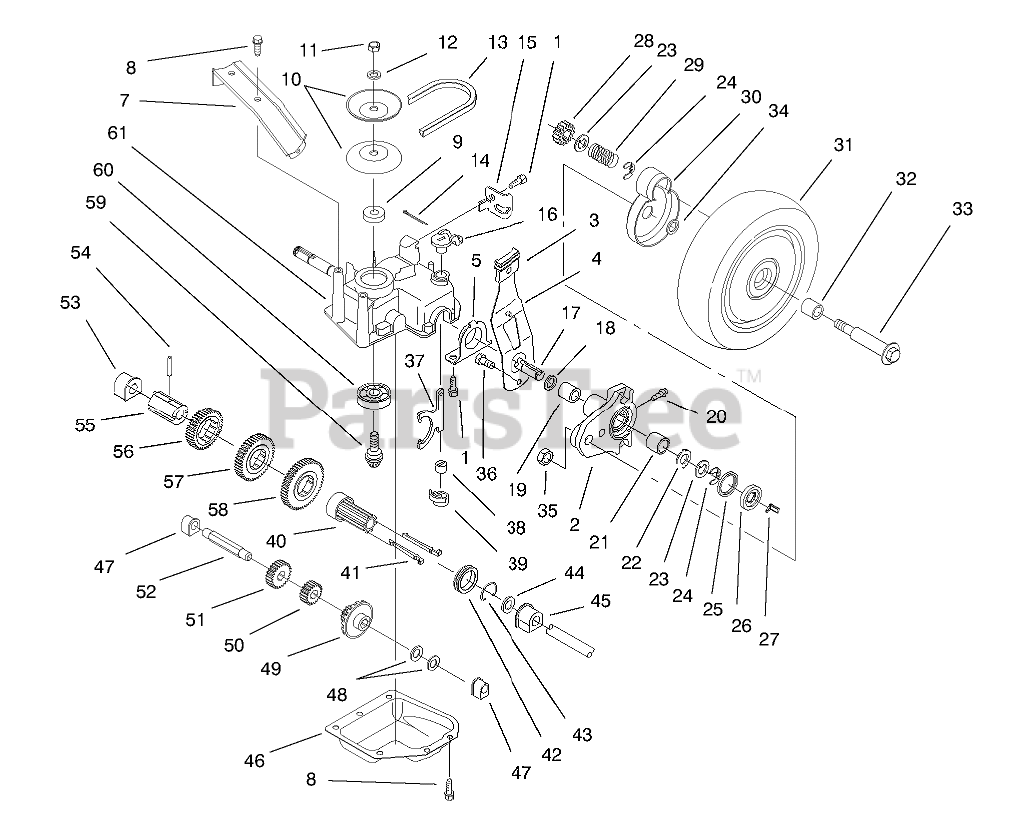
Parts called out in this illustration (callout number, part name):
1	SCREW-HWHTF
2	Pivot Arm Assembly (Incl. Ref. #19-21)
3	KNOB-ARM
4	SPRING ARM ASM
5	CAP-END
7	Bracket-BeltGuide
8	SCREW-HWHTF
9	SPACER
10	Pulley Half
11	NUT-HEX
12	WASHER-FLAT
13	V-BELT
14	PIN-COTTER
15	RETAINER-CABLE
16	LEVER-SHIFT
17	SHAFT-OUTPUT
18	O-RING
19	BUSHING
20	FITTING-GREASE
21	BEARING-ROLLER
22	WASHER-ARM, PIVOT
23	WASHER-THRUST, KEYED
24	RING-CLIP, LOCKING
25	RING-FRICTION
26	WASHER-CLUTCH
27	KEY-ROCKING, LH
28	GEAR-PINION
29	SPRING-COMPRESSION
30	COVER-WHEEL
31	Wheel Tire & Gear Assy. (Incl. Ref. #32)
32	BUSHING
33	WHEEL BOLT
34	SPACER-COVER, WHEEL
35	NUT-LOCK
36	SCREW-HSH, THREAD FORMING
37	YOKE-SHIFT
38	BUSHING-YOKE
39	RETAINER-FORK, SHIFT
40	SLEEVE-KEY, SHIFT
41	KEY-SHIFT
42	COLLAR-SHIFT
43	CLIP-SPRING
44	WASHER-PLAIN
45	BUSHING-OUTPUT
46	Cover-Gearcase
47	BUSHING
48	WASHER-THRUST
49	Gear-Bevel
50	PINION-20T
51	PINION-25T
52	SHAFT-INTERMEDIATE
53	BUSHING
54	PIN-SPRING
55	SLEEVE-GEAR
56	GEAR-39T
57	GEAR-44T
58	GEAR-49T
59	Gear-Pinion
60	BEARING-BALL
61	CASE-GEAR, UPPER
